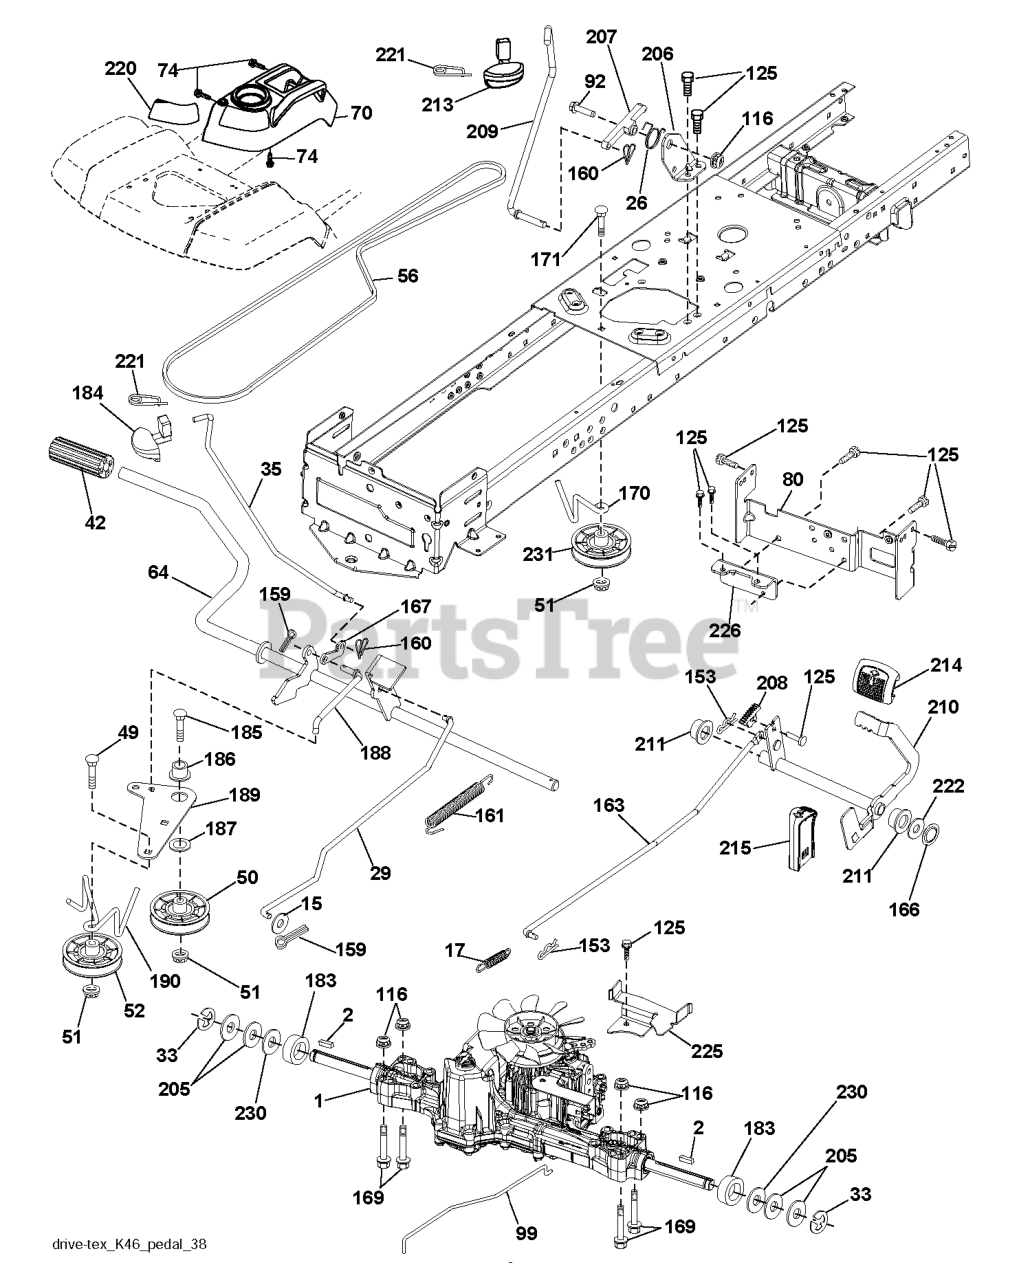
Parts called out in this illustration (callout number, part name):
2	SQUARE KEY
15	WASHER
17	SPRING.BRAKE.K46.GREEN
26	SPRING.RETURN.CRUISE
29	ROD.BRAKE.K46
35	ROD.BRAKE.PARKING.GT.H
42	PEDAL COVER T
50	IDLER.FLAT.910.OFFSET
51	NUT LOCK FLG 3/8-16 UNC
52	IDLER.V-GROOVE.910.OFFSET
56	V-BELT.MOWER.92.40.42/K46
64	SHAFT.ASM.PEDAL.BRK.CNTR
70	RP CONSOLE.ASM.PCH.W/TB
74	SCREW.HI-LO.CONSOLE
80	STRAP TORQUE
92	BOLT
99	ROD.SPRING.BYPASS.K46.LT.Z
116	NUT LOCK HEX FLANGE 5/16-18
125	SCREW
143	Screw 5/16-18 x 1/2 Hex, Self Tapping 5/16-18 x 1/2
153	RETAINER M
159	COTTER PIN
160	RETAINER CLIP
161	SPRING, RETURN LT
163	ROD.CONTROL.PEDAL.K46
166	NUT.PUSH.625.2006
167	LATCH.BRAKE.SPRING
169	BOLT HEX 5/16-18 GR 5
170	KEEPER.V-IDLER.CENTER.
183	SPACER AXLE
184	HANDLE.PARKG.BRK.HUSQ X667
186	SPACER.RETAINER
187	WASHER 12/32X2X10GA
188	RP.LINK.CLUTCH.GROUND.DRIVE
189	BELLCRANK.GROUND.DRIVE.TEX.
190	KEEPER.BELLCRANK.DRIVE
196	SCREW 3/8-16X1
197	LINK.CLUTCH.ANIT-ROTAT
206	BRKT.MOUNT.LATCH.CRUIS
207	LATCH.CONTROL.CRUISE
208	GEAR.SECTOR.CONTROL.CR
209	ROD.CONTROL.CRUISE.GT.
210	ROCKER.ASM.PEDAL.CONTR
211	BEARING.NYLON
213	KNOB.CONTROL.CRUSIE.HU
214	PEDAL.FORWARD.TEX.GT.4
215	PEDAL.REVERSE.TEX.GT.4
216	BRACKET.PULLEY.IDLER.W/TEX
220	REFLECTOR.RH.TEX GT
221	RETAINER.SPRING.CLIP.H
222	WASHER 21/32 X 1-1/4 X 10 GA.
225	KEEPER.BELT.TRANSAXLE.K46
226	BRACKET.MOUNT.TORQUE.K46.TLT
230	WASHER.HARDENED
